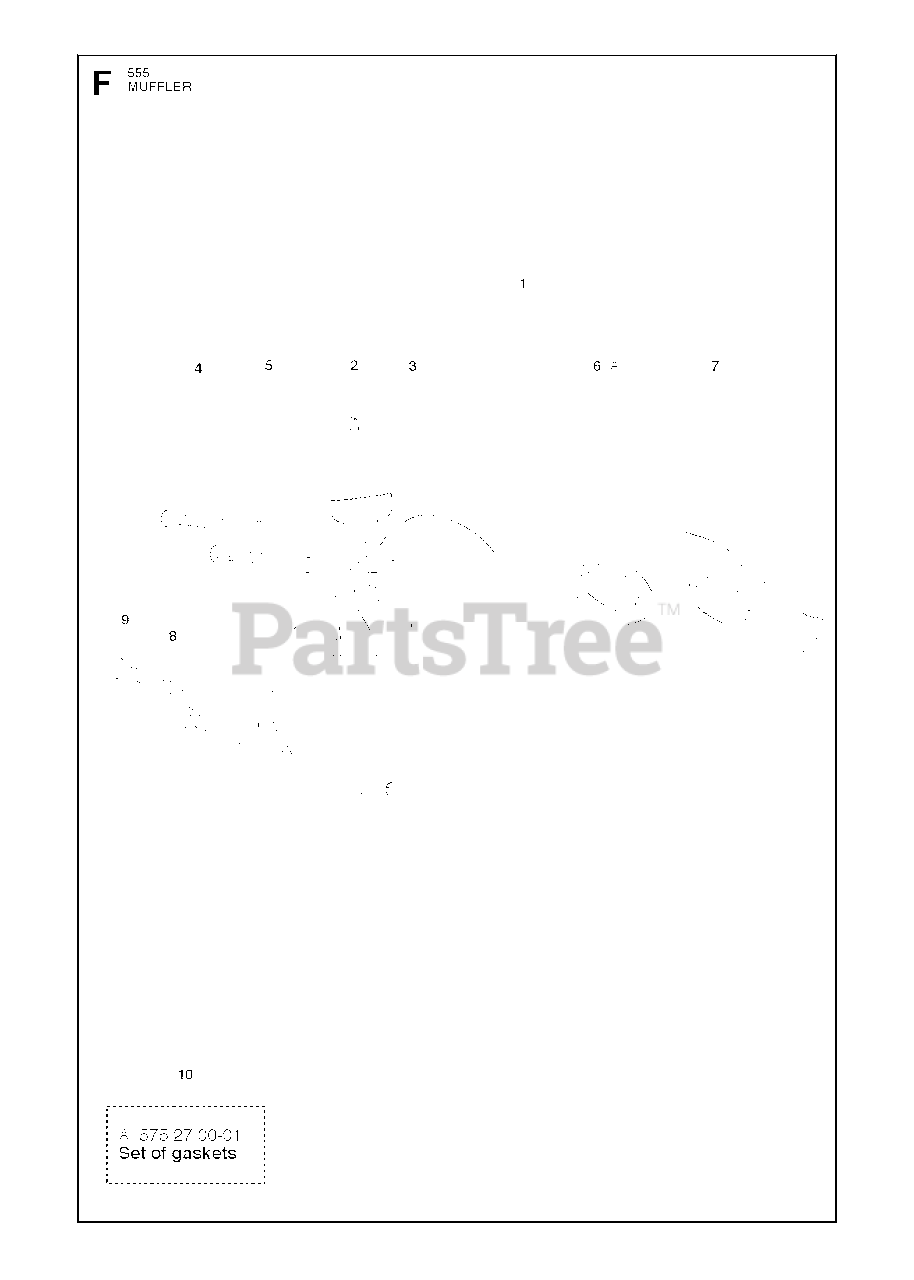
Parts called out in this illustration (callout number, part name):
1	MUFFLER KIT
2	SCREW
3	SPARK ARRESTER
4	SCREW
5	SLEEVE MUFFLER
6	GASKET MUFFLER
7	HEAT DEFLECTOR
10	RP GASKET KIT
